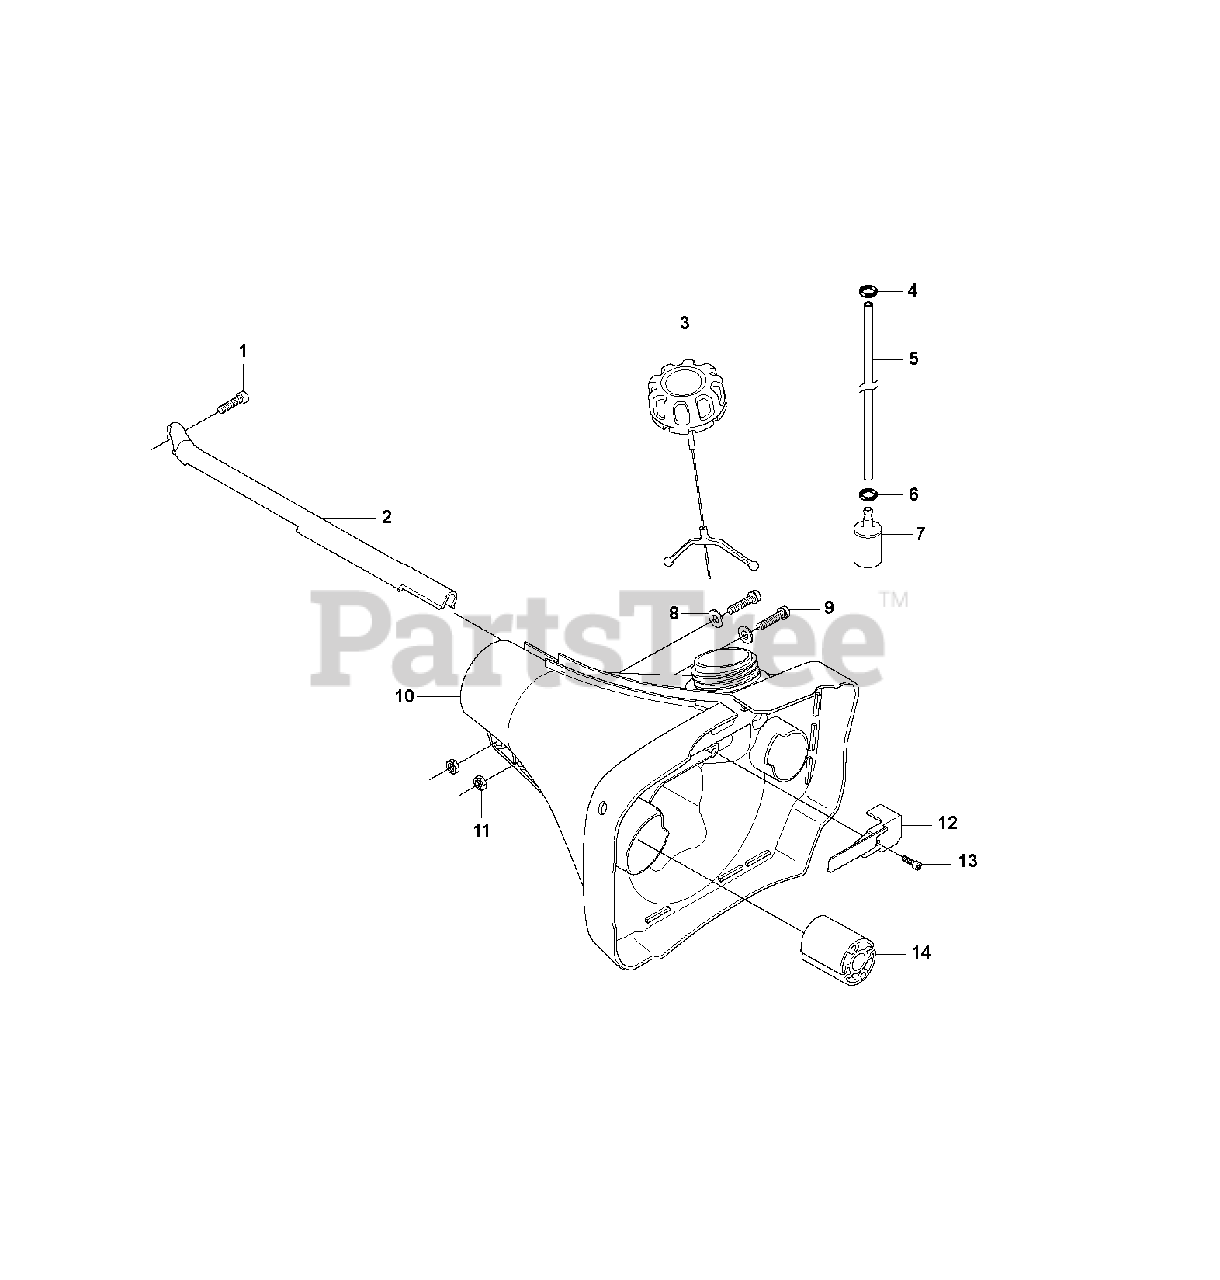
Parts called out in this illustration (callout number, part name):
2	TUBE (FC,FCS)
2	TUBE (BC)
3	%WINTER TANK CAP
5	FUEL HOSE
7	FUEL FILTER
8	WASHER 5.3X12
10	TANK UNIT
14	%BELLOWS
